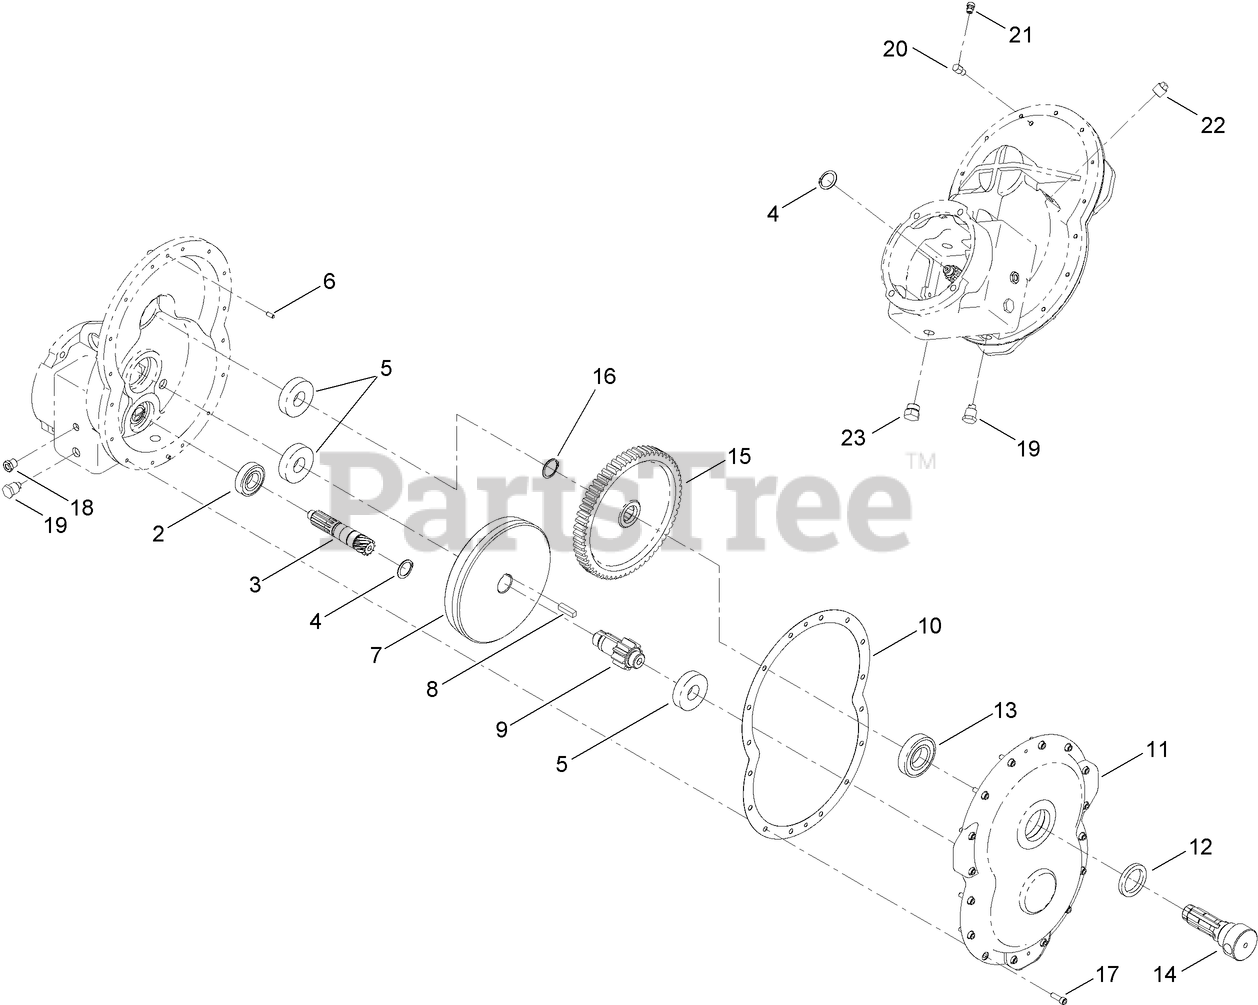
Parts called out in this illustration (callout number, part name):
2	BEARING-BALL
3	SHAFT-INPUT, PINION
4	RING-EXTERNAL
5	BEARING-ROLLER
7	GEAR-HELICAL
8	KEY-SQUARE
9	PINION
10	GASKET-GEARCASE
11	COVER-GEARCASE
12	SEAL-SHAFT
13	BEARING-BALL
14	SHAFT-OUTPUT, GEARCASE
15	GEAR-SPUR
16	RING-SNAP, EXTERNAL
17	SCREW-HSH
18	PLUG-SIGHT, OIL
19	PLUG-HH, MAGNETIC
20	ELBOW-CONNECTION
21	BREATHER-ALEMITE
